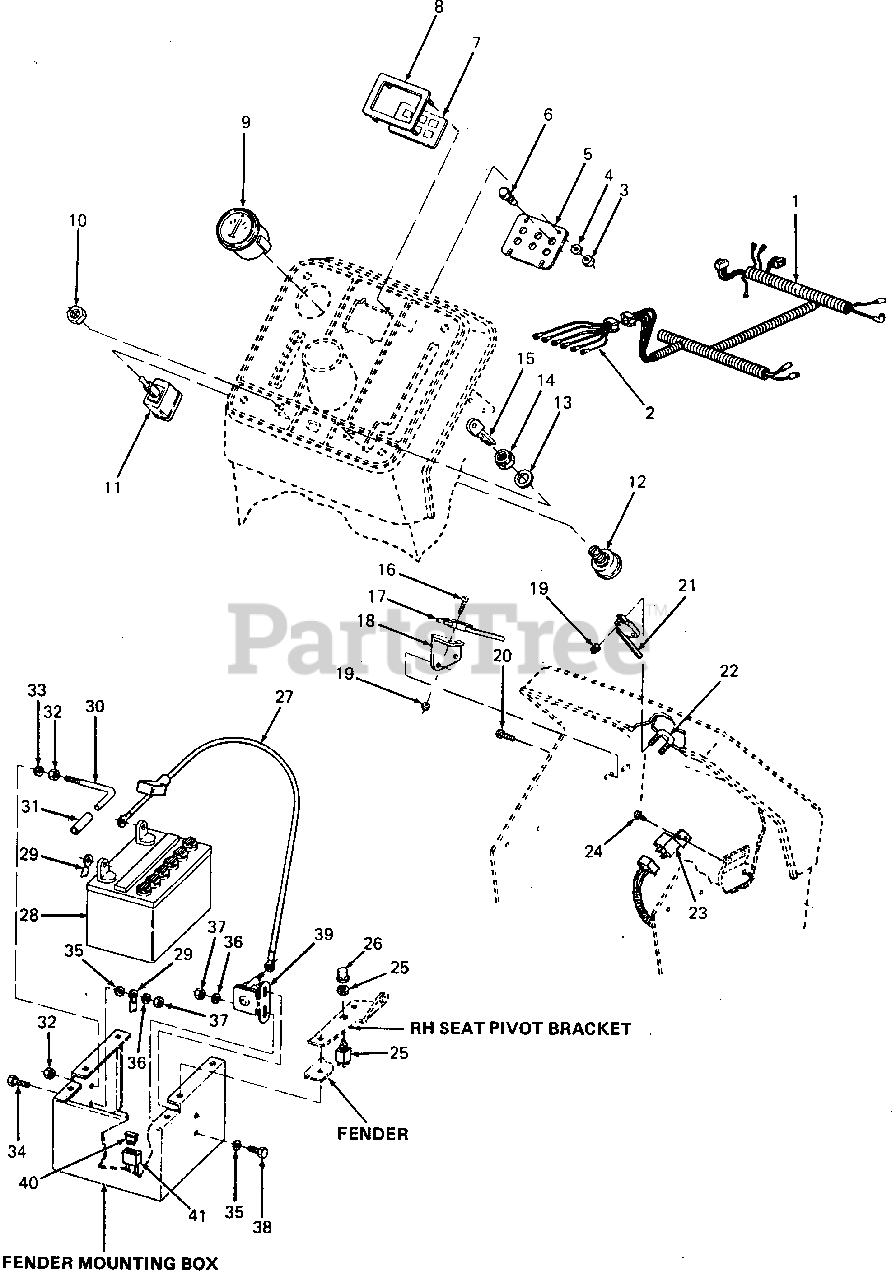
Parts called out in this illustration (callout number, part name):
1	Harness, Wire
2	Harness, Indicator Wire
3	Nut, Self-Threading Pal
4	Washer, Rubber, .18 X .50 X .06 Thk
5	Plate, Indicator
6	Lamp, Indicator
7	Label, Indicator
8	Bezel, Light
9	Ammeter
10	Nut, Hex, 1/2-27 X .100 Thk
11	Switch, PTO
12	Switch, Ignition Key
13	Washer, Flat
14	Nut, Ignition Switch
15	Key, Ignition (Set of 2)
16	Screw, Hex Hd Mach, #4-40 X .75 Lg
17	Switch, Micro
18	Plate, Switch
19	Nut, Hex Insert Lock, #4-40
20	Screw, Hex AB Tapp, 1/4 X .62 Lg
21	Switch, Micro
22	Screw, Switch
23	Relay
24	Screw, Pan Hd Tapp, #12 X .50 Lg
25	Switch w/Nut
26	Boot, Switch
27	Wire, Positive Battery
28	Battery, 12 Volt
29	Wire, Ground, 11.5 Lg
30	Pin, Locking
31	Fuel Line, 2 in. Long
32	Nut, Hex, 5/16-24 GR5
33	Washer, Lock, 5/16
34	Screw, Hex Cap, 1/4-20 X .62 Lg GR5
35	Washer, Int Ext Lock, 1/4 X 3/4
36	Washer, Flat, .281 X .73 X .063 Thk
37	Nut, Hex Patch Lock, 1/4-20
38	Screw, Hex Cap, 1/4-20 X .50 Lg GR5
39	Solenoid, 12 Volt
40	Fuse, Auto Type, 20 Amp
41	Fuse Holder
